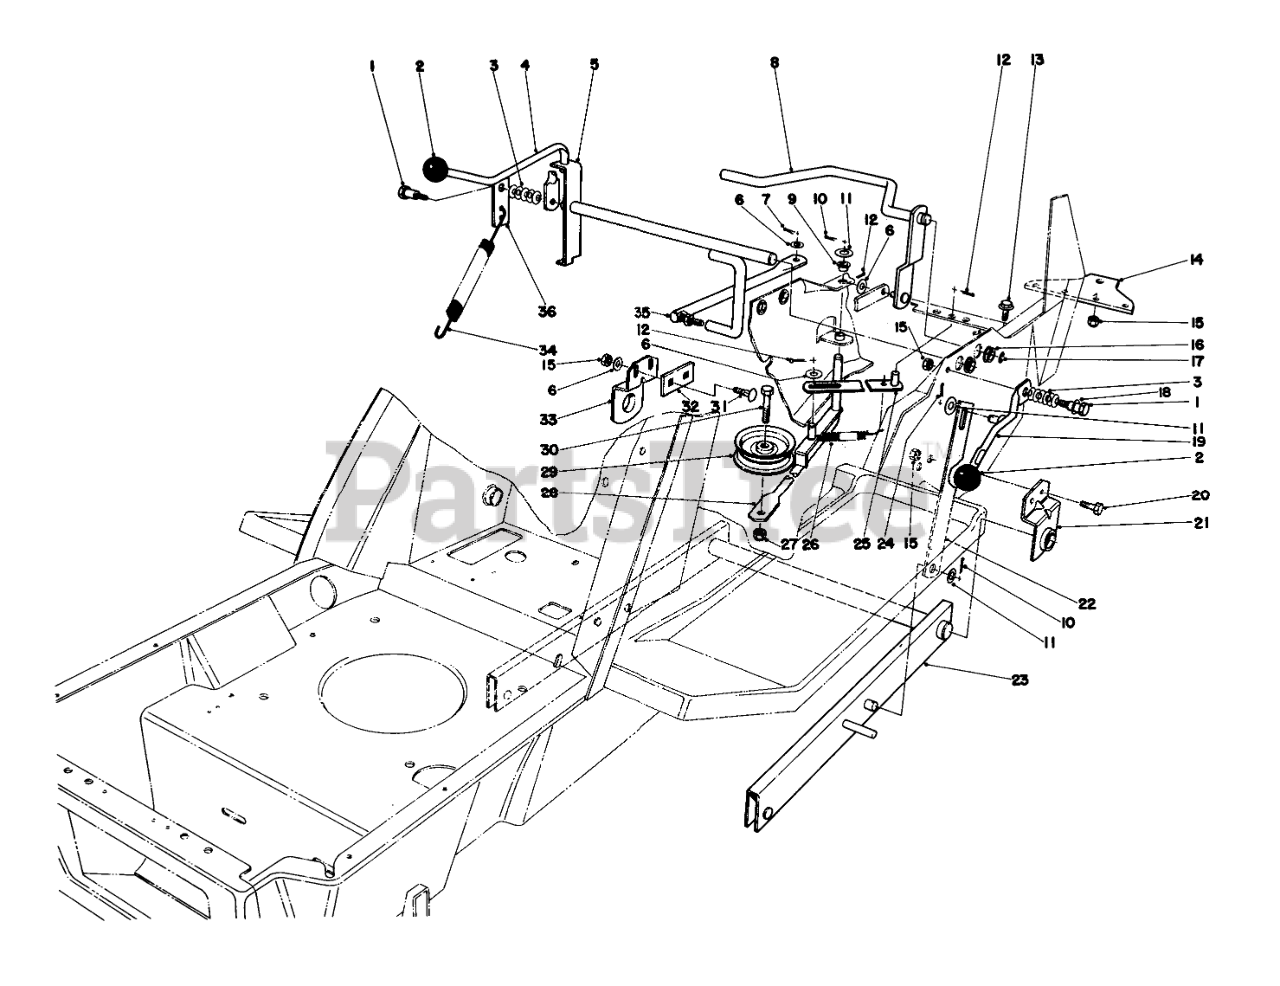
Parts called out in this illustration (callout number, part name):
1	BOLT-SHOULDER
3	WASHER-BELLEVILLE
4	SHIFT LEVER BO
5	Shim Lever
6	WASHER-PLAIN
7	PIN-COTTER
8	CLUTCH ACTUATOR WA B
9	BUSHING-NYLINER
10	PIN-COTTER
11	WASHER-FLAT
12	PIN-COTTER
13	SCREW-HHF
14	HITCH PLATE R
15	NUT-LOCK, NI
16	Nyliner
17	E-RING
18	WASHER-FLAT
19	HOC HANDLE WA B
20	SCREW-HH
21	LH PIVOT BAR RET B
22	HOC LINK B
23	Bar-Pivot
24	PIN-COTTER
25	SPRING RET WA B
26	DECK TENSION SPRNG O
27	NUT-LOCK, CONE
28	IDLER ARM WA BO
29	IDLER PULLEY
30	SCREW-HH
31	BOLT-CARR
32	SPACER
33	RH PIVOT BAR RET B
34	TRACTION SPRING
35	SHIFT ARM BO
36	BRKT-COBALANCE SPRING
